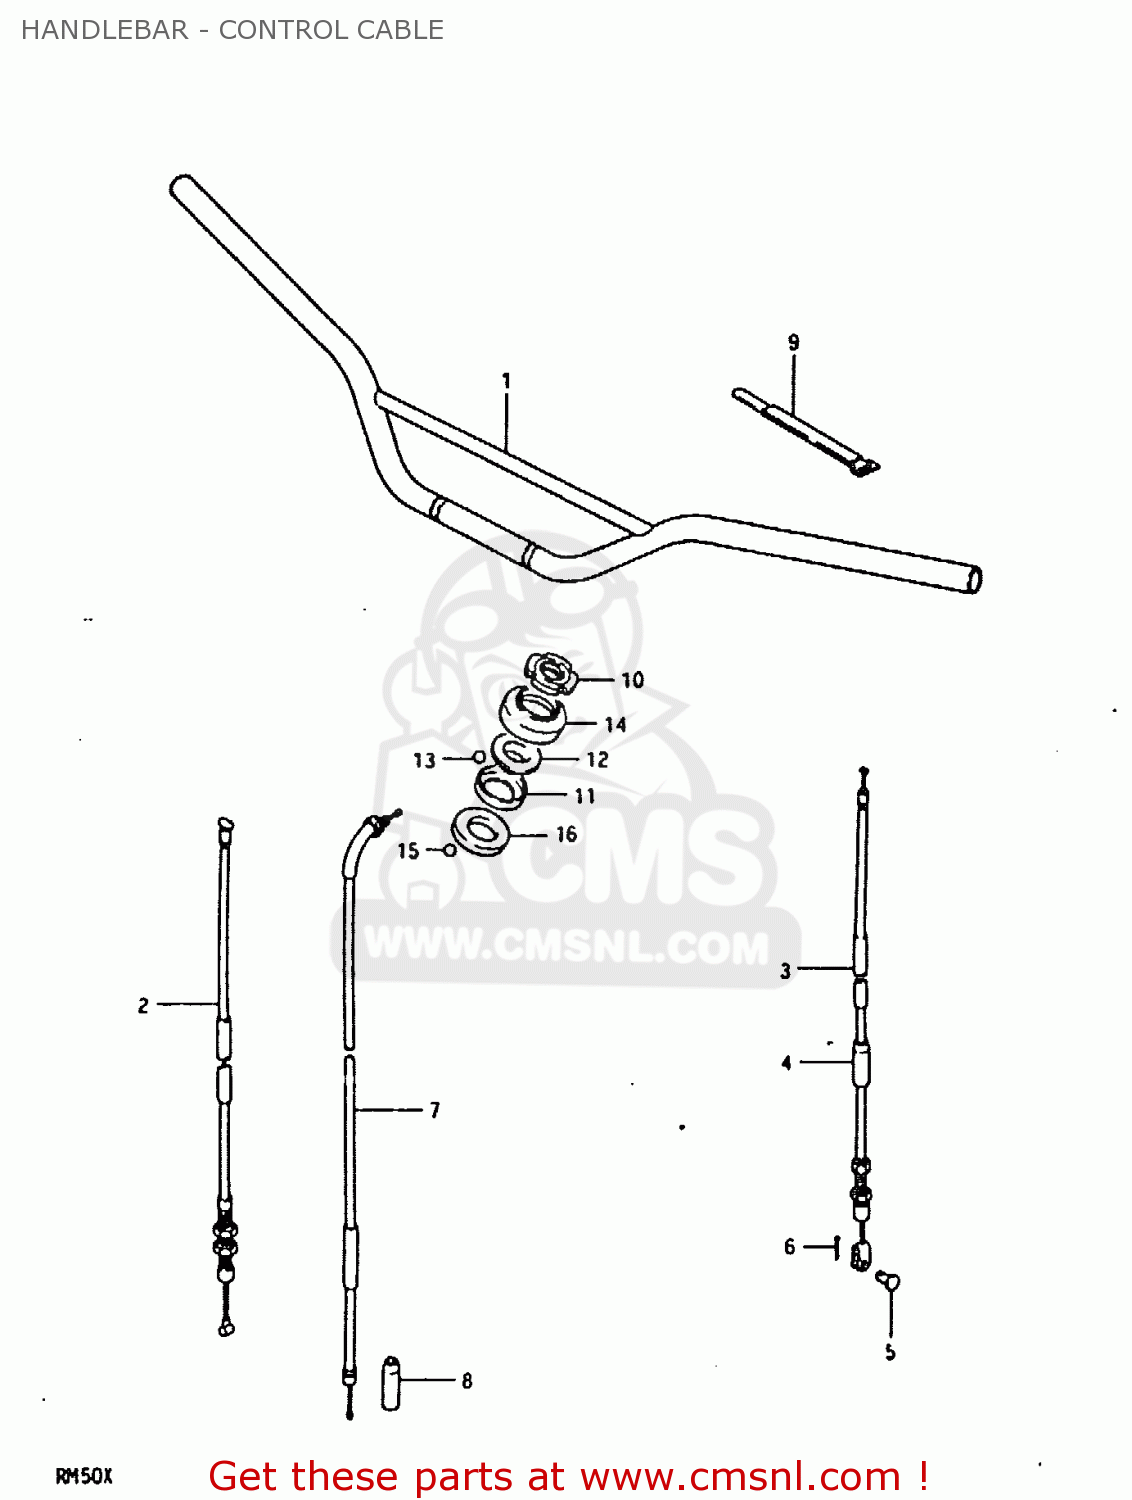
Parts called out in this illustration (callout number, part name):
1	HANDLEBAR
2	CABLE,FRONT BRAKE
3	CABLE ASSY,CLUTCH
4	SEAL,DUST(7X18X30)
5	PIN(L:13)
6	PIN
7	CABLE ASSEMBLY,THROTTLE
8	SEAL,DUST(7X18X30)
9	CLAMP
10	NUT,STEERING STEM(25X44X10)
11	RACE,STEERING INNER UPR
12	RACE,STEERING OUTER UPR
13	BALL
14	DUST SEAL,STEERING UPR
15	BALL
16	LACE,STEERING INNER LWR
